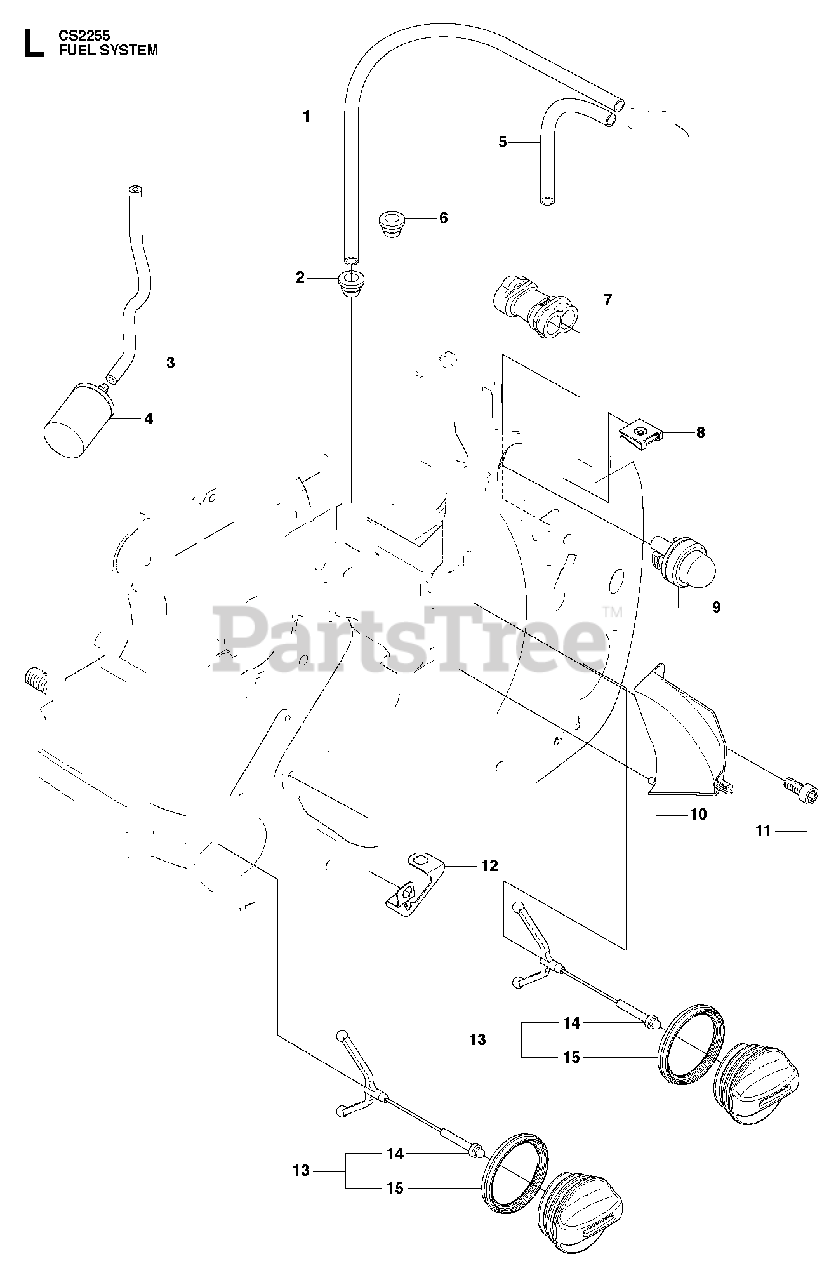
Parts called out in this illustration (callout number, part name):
2	FUEL TANK BUSHING
3	FUEL HOSE
4	FUEL FILTER
5	FUEL HOSE/38MM
6	FUEL TANK BUSHING
7	GUIDE SLEEVE CARB
9	AIR PURGE BUBBLE
12	SWITCH PLATE
13	TANK CAP ASSY
14	HOLDER
15	SEALING
